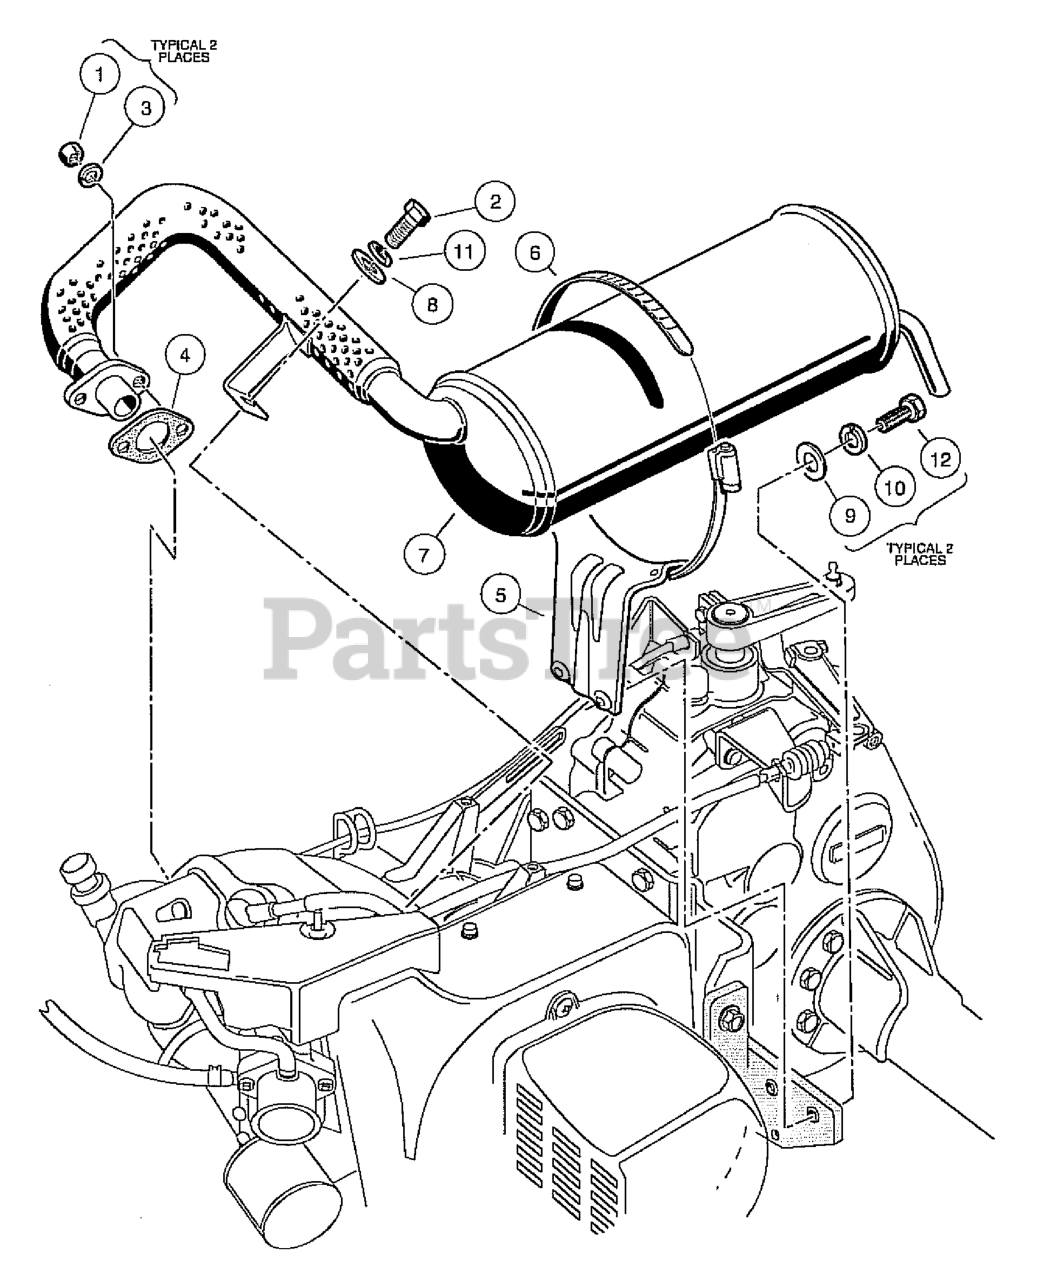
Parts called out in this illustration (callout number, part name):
1	NUT, M8-1.25 HEX
2	SCREW
4	GASKET, OHV EXHAUST
5	BRACKET, MUFFLER MOUNTING
6	CLAMP, 5" MUFFLER HOSE
7	EXHAUST SYSTEM, FE290
8	WASHER, 5/16 TYPE A FLAT
9	WASHER 1/4 FLAT
10	LOCKWASHER, 1/4 HELICAL SPLIT
11	LOCKWASHER, 5/16 SPLIT
12	SCREW, 1/4-20 X .75 HEX
